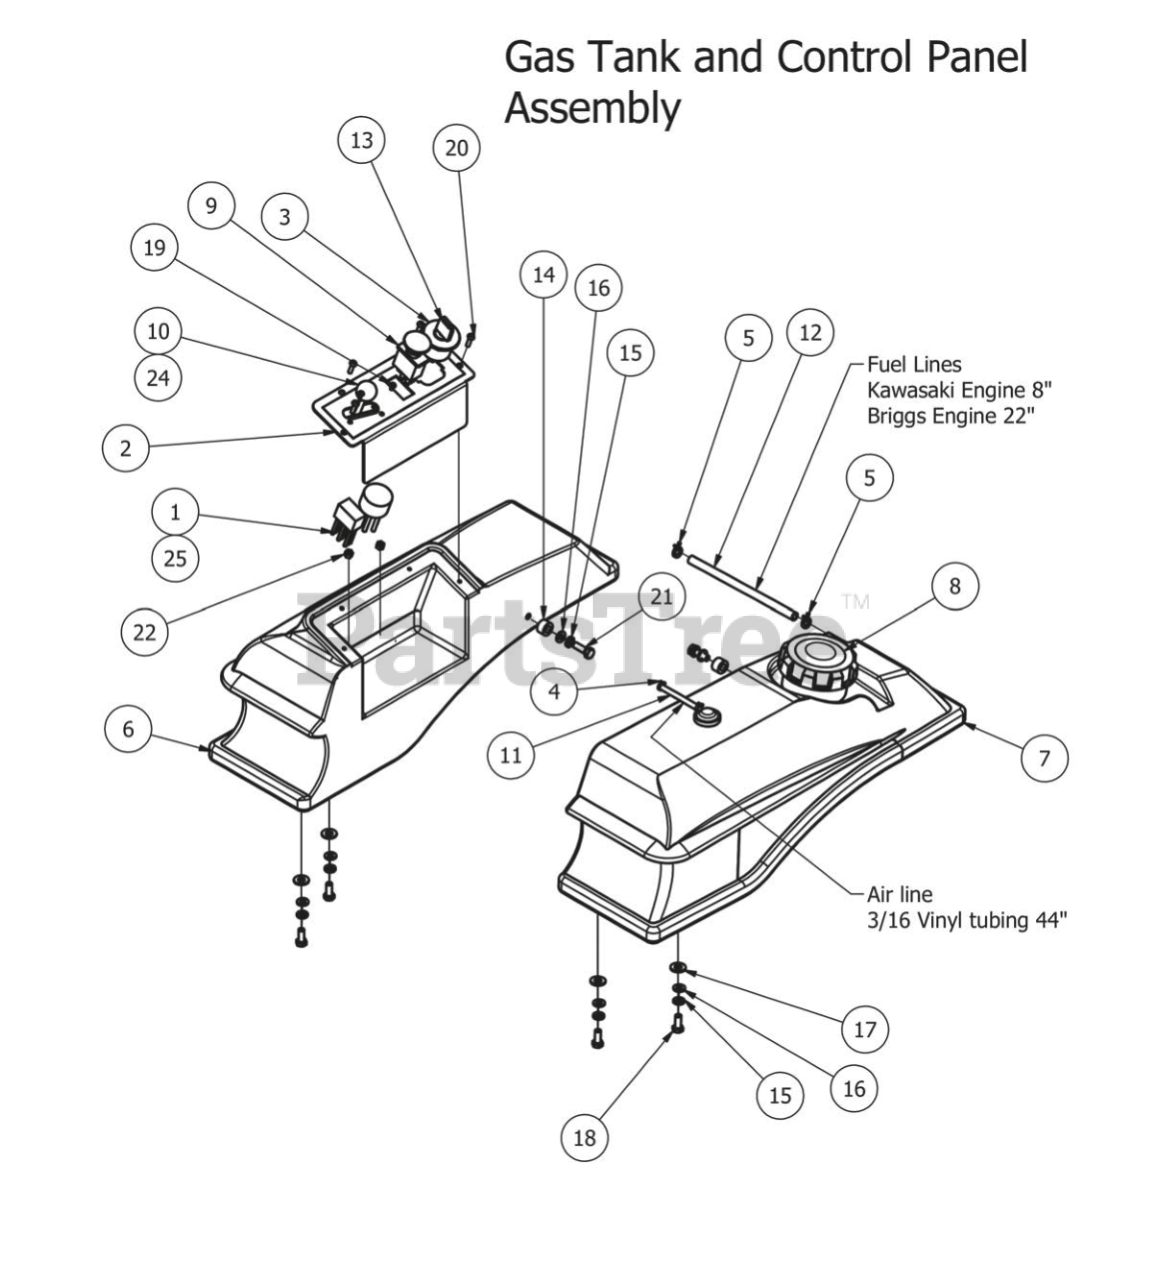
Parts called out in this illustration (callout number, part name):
1	Wiring harness
2	MZ Control Panel
3	Ignition Switch
4	3/16 vinyl clamp
5	1/4 fuel clamp
6	Fender Console
7	3 Gallon Fuel Tank/MZ/2012 EPA
9	PTO Engager
10	Throttle Lever W/Choke
11	3/16 vinyl tubing
12	1/4" fuel line hose sold by the Foot
13	Ignition Key
14	Tank spacer
15	5/16" Lock Washer
16	1/4" Flat Washer
17	.360 ID Plastic Washer
18	5/16" x 3/4" Hex Bolt
19	10-24 X 5/8 BS C/S 18-8 SS
20	10-32 x 3/8" Button Socket Head Bolt
21	5/16" x 1" Bolt
22	10-24 Nylon Insert Locknut
24	Throttle-21Hp MZ Only
25	Relay Terminal
